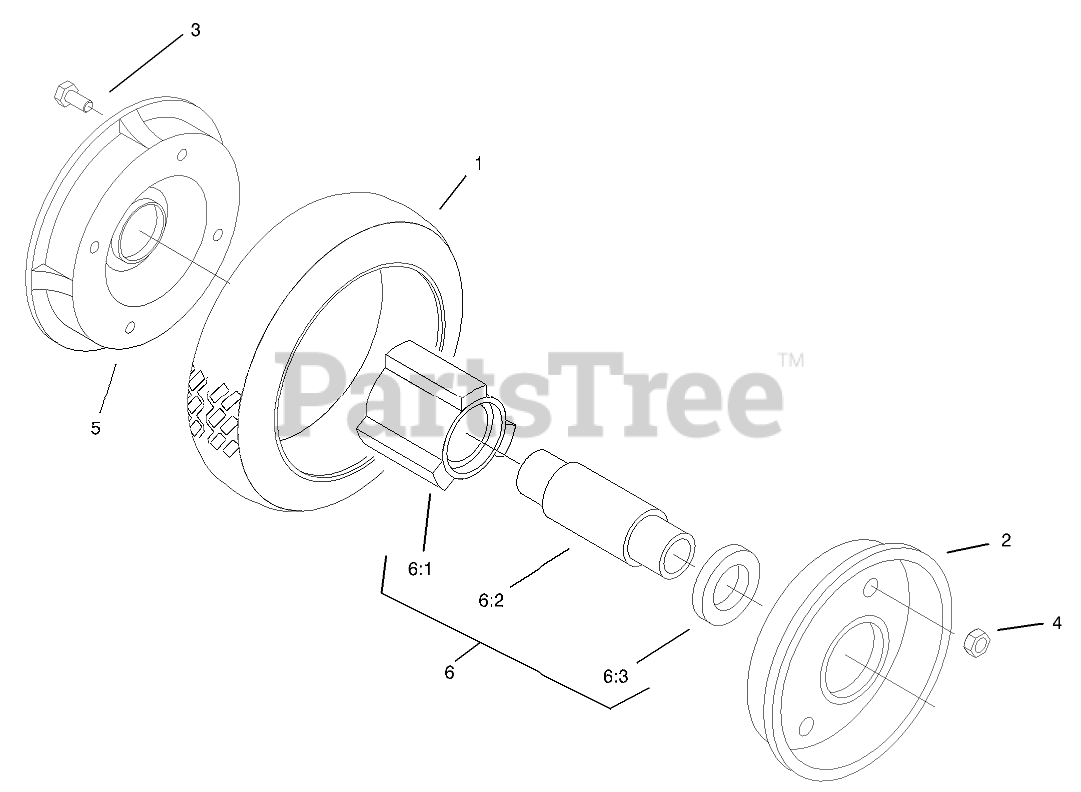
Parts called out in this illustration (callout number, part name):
2	PLATE-WHEEL, HALF
3	SCREW-HH
4	NUT-LOCK, NI
5	WHEEL HALF AND GEAR ASM
6	HUB and BEARING ASM
6:1	HUB-BEARING
6:2	SPACER-BEARING
6:3	BEARING-WHEEL
